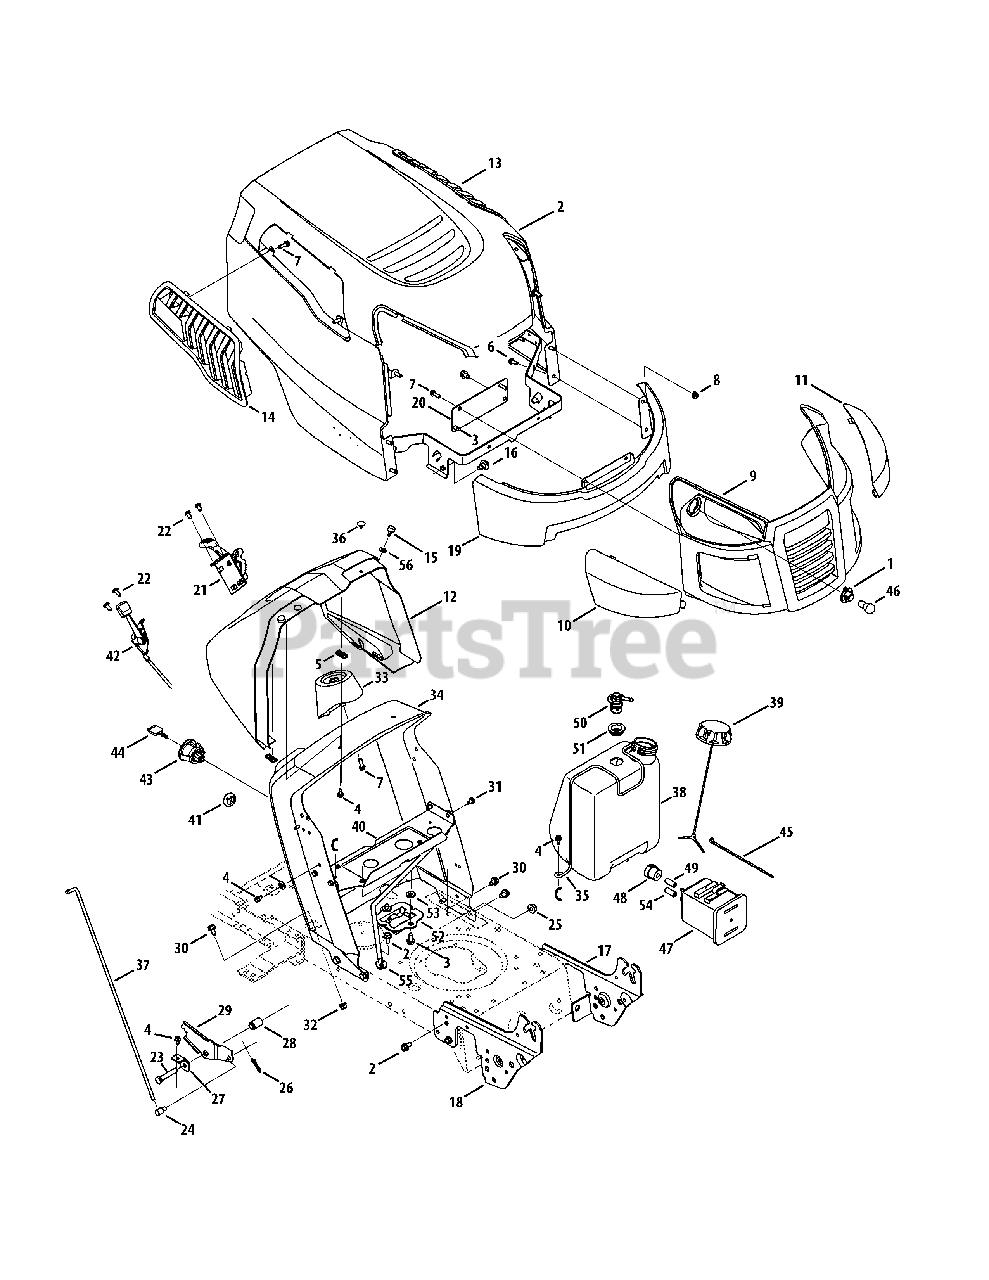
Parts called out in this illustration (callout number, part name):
1	Bulb Socket
2	Hood Assembly
3	Screw, 5/16-18 x .750
4	Hex Washer Screw, 1/4-20 x .500
5	Tin Clip Nut, 1/4-20
6	Hex Screw, 1/4-20 x .620
7	Screw, 1/4 x .750
8	Nut, Hex Flange Insert Lock, 1/4-20
10	Headlight Lens, RH
11	Headlight Lens, LH
12	Dash Collar
13	Hood Scoop, LH
14	Hood Scoop, RH
15	Bumper
16	Shoulder Screw, 5/16-18
17	Left Support Pivot Bracket
18	Right Support Pivot Bracket
19	Lower Grill
20	Lower Grill Bracket
21	Parking Brake Lever Assembly
22	Self-Tap Screw, 1/4-20
23	Hex Head Screw, 3/8-16
24	Ferrule, 1/4-20 x 1.00
25	Nut, Hex Flange Insert Lock, 3/8-16
26	Cotter Pin
27	Speed Latch Tab
28	Flange Spacer
29	Speed latch
30	Self-Tap Screw, 1/4-20
31	Hex Screw, 1/4-15
32	Nut, Hex Flange Lock, 5/16-18
33	Steering Support
35	Fuel Tank Support Rod
36	Ratchet Clip
37	Speed Selector Control Rod
38	1.38 Gallon Fuel Tank
39	Fuel Cap
40	Gas Tank Support Bracket
41	Choke Plug
42	Throttle/Choke Assembly
43	3-position Key Switch
44	Key (2 pack)
45	Cable Tie
46	Headlight Bulb
47	Carbon Canister
48	Filter Vent
49	Low Perm Fuel Line 3/16 White
50	Rollover Valve
51	Rubber Grommet
52	Canister Bracket
53	Flat Washer, .344 x.750 x .120
54	Low Perm Fuel Line 7/32 Yellow
55	Dash Support Rod
56	Flat Washer, .250 x .630 x .052
